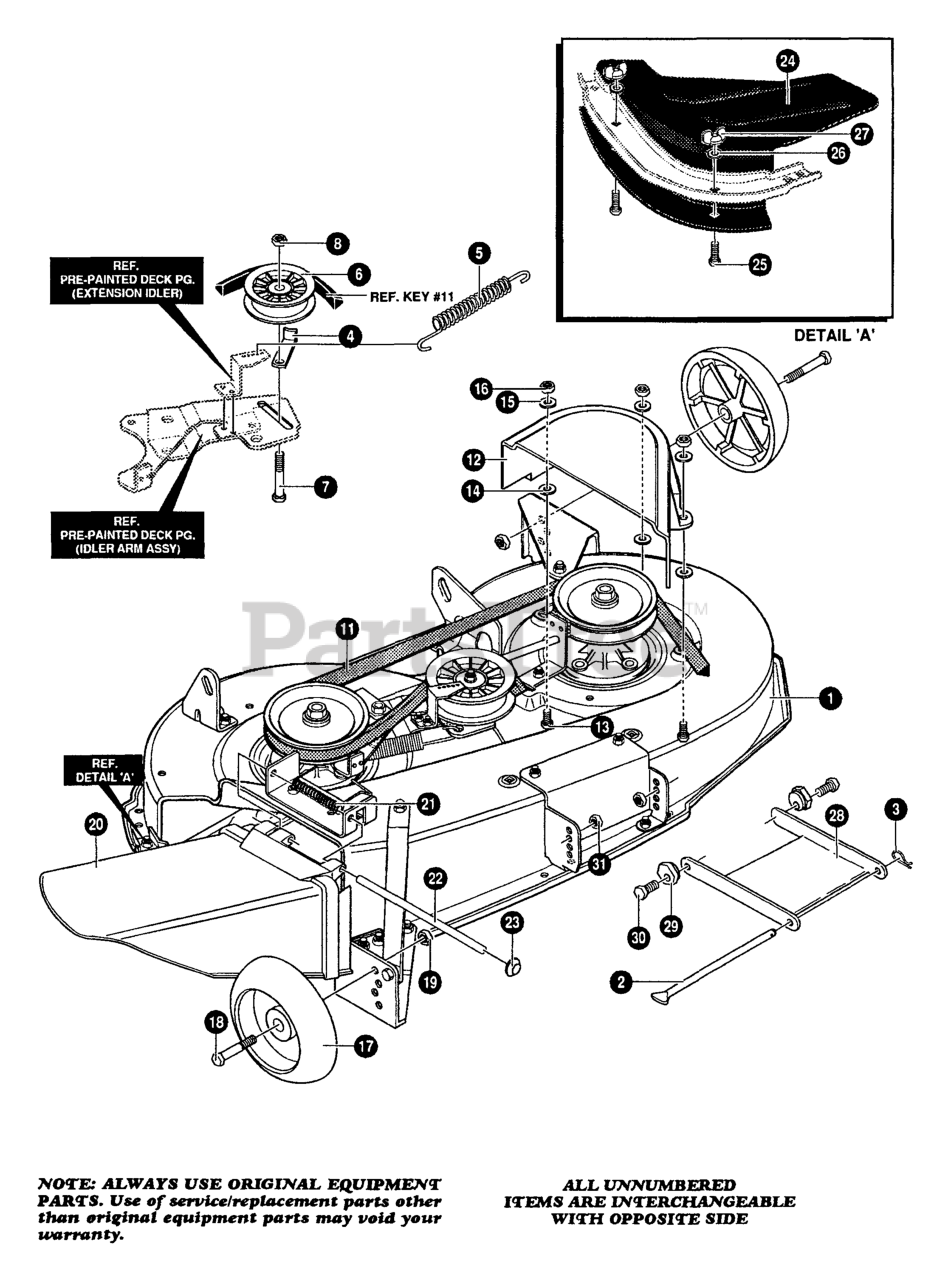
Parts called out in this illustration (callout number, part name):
1	43" DECK, W/ZIRKS
2	ROD, DECK HITCH
3	PIN, HAIR
4	RETAINER, BELT
5	SPRING, TENSION
6	PULLEY, IDLER
7	BOLT, 3/8-16 x 1.75
8	NUT, 3/8-16
11	BELT, V 5L 86.00
12	GUARD, BELT, LH
13	BOLT, 5/16-18 x .75
14	PUSHNUT, BOLT RETAINER
15	WASHER, FLAT .344 x .69 x .065
16	NUT, 5/16-18
17	GAUGE WHEEL
18	BOLT, .500 X 1.390
19	NUT, 3/8-16
20	CHUTE DEFLECTOR
21	SPRING, TORSION
22	ROD, PIVOT DECK
23	NUT, PUSH ON CAP
24	MULCHER PLUG
25	BOLT, 5/16-18 x .75
26	WASHER, .320 x .61 x .03
27	NUT, WING
28	BRACKET, LINK DECK FRONT
29	NUT, ADJUST
30	SCREW, 5/16-18 x 1.00
31	NUT, 5/16-18
